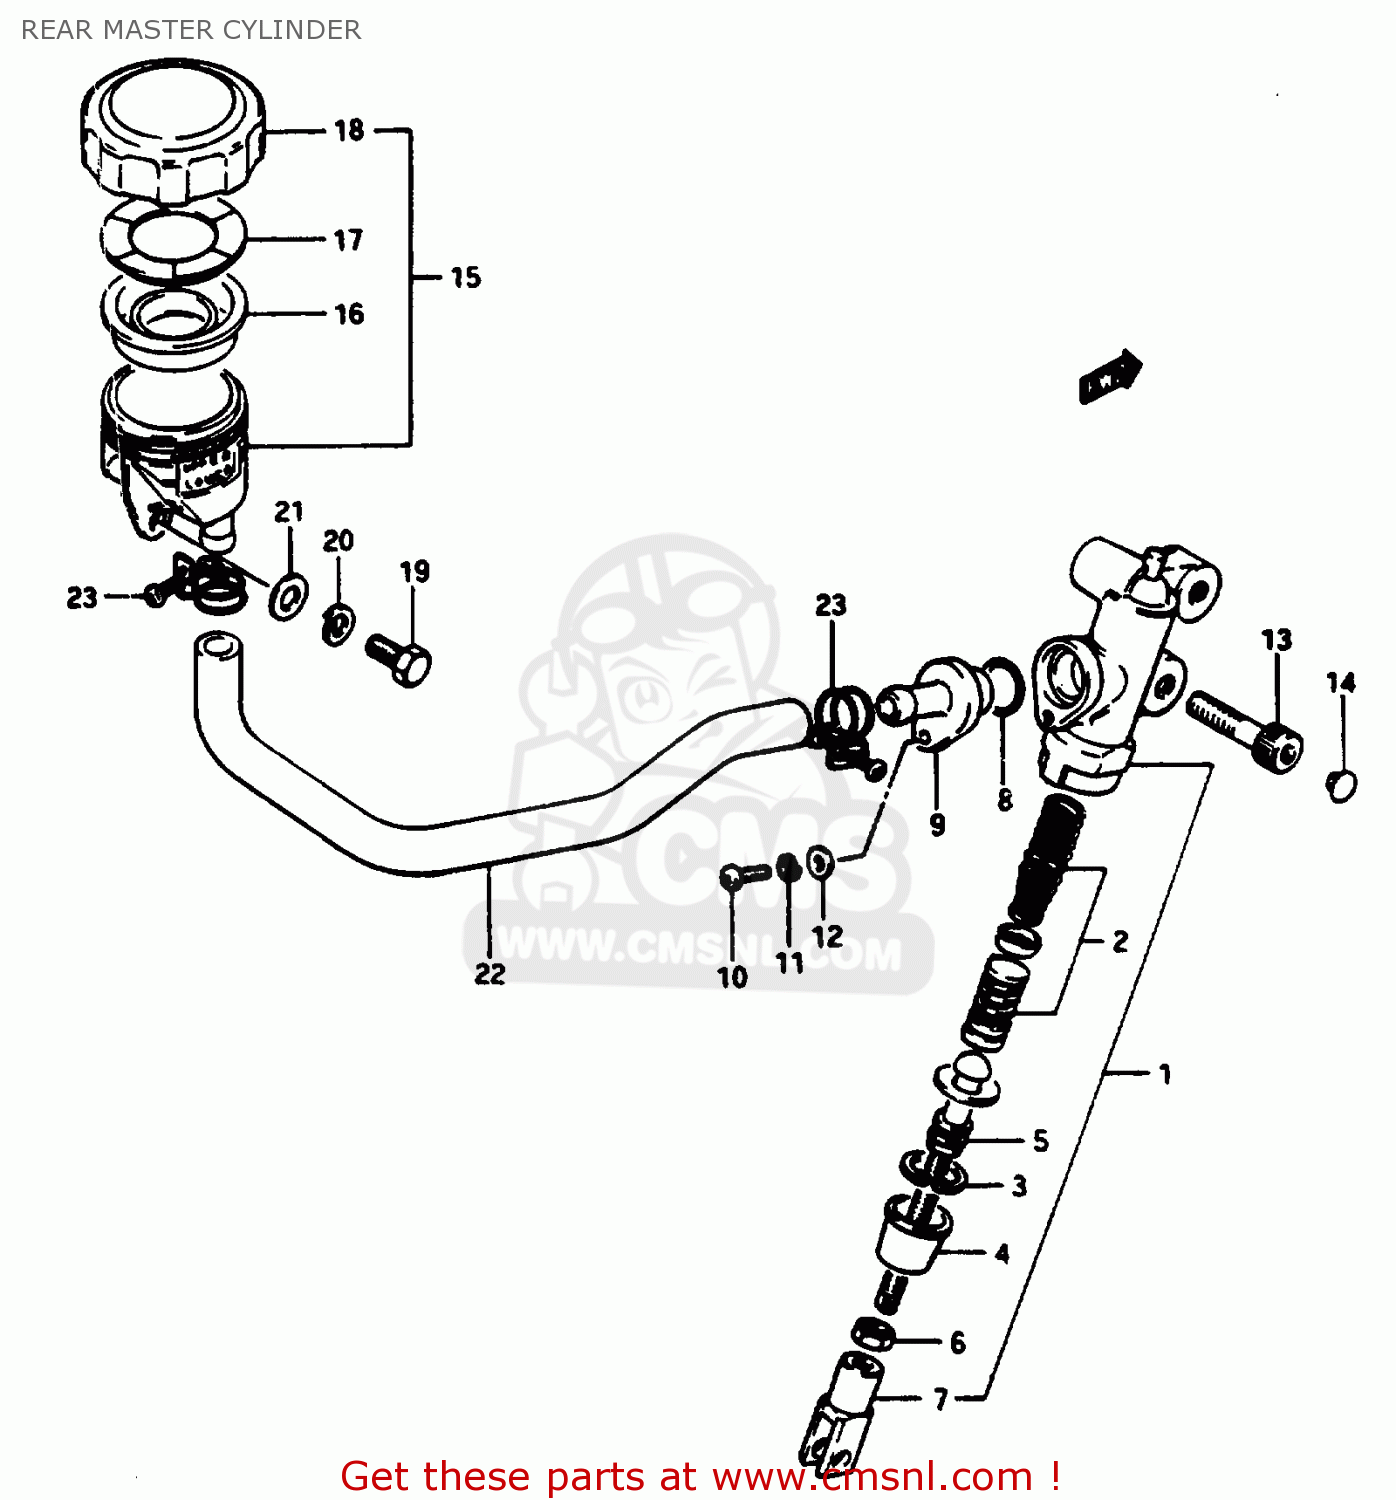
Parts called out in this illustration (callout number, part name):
1	CYLINDER ASSEMBLY,REAR MASTER
2	PISTON/CUP SET
3	CIRCLIP
4	BOOT
5	ROD,PUSH
6	NUT,MASTER CYLINDER
7	YOKE
8	O RING
9	CONNECTOR
10	SCREW
11	LOCK WASHER
12	WASHER
13	BOLT, FRONT RH
14	CAP(OD:10)
15	TANK ASSEMBLY,RESERVOIR
16	DIAPHRAGM
17	PLATE,DIAPHRAGM
18	CAP
19	BOLT 6X16
20	WASHER,LOCK
21	WASHER
22	HOSE,RESERVOIR TANK
23	CLAMP
